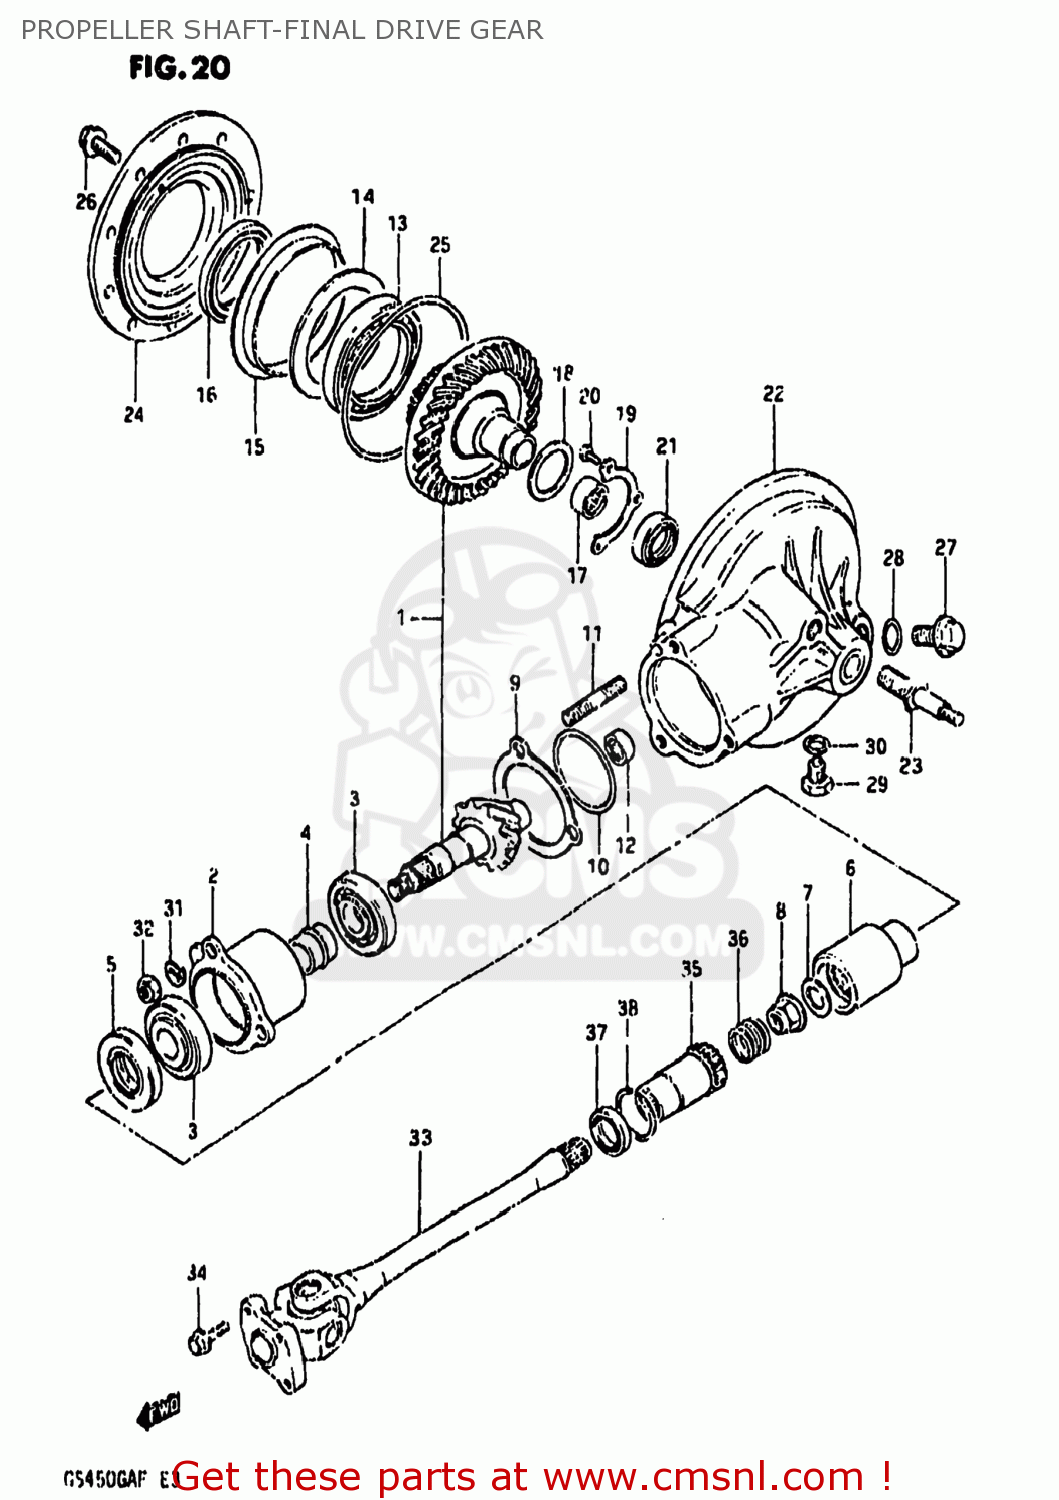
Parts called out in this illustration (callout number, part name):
1	GEAR SET,FINAL BEVEL (N
2	HOUSING,DRIVE GEAR
3	BEARING
4	SPACER
5	SEAL,OIL(32X54X7)
6	GEAR,FINAL DRIVE
7	WASHER(14X29X4)
8	NUT
9	SHIM,DRIVE GEAR HOUSING
10	O RING(D:2.4,ID:62.6)
11	STUD
12	BEARING
13	BEARING(70X110X13)
14	SHIM,DRIVEN GEAR BEARING T0.35
15	PLATE,FINAL DRIVEN BRG OIL
16	SEAL,OIL(70X96X16)
17	BEARING(32X46X17.7)
18	SHIM,FINAL DRIVEN GEAR
19	RETAINER,FINAL DRIVEN GEAR BRG
20	SCREW 6X12
21	SEAL,OIL(30X42X7)
22	CASE,FINAL GEAR
23	STUD
24	CASE,FINAL GEAR BEARING
25	O RING(D:3.5,ID:131.6)
26	BOLT
27	PLUG
28	O RING(D:2.4,ID:17.8)
29	PLUG
30	GASKET(14X19.2X2) (NAS)
31	LOCK WASHER
32	NUT
33	SHAFT ASSEMBLY,PROPELLER
34	BOLT(8X17)
35	COUPLING,PROPELLER SHAFT
36	SPRING
37	SEAL,OIL(30X40.5X5.5)
38	CIRCLIP
